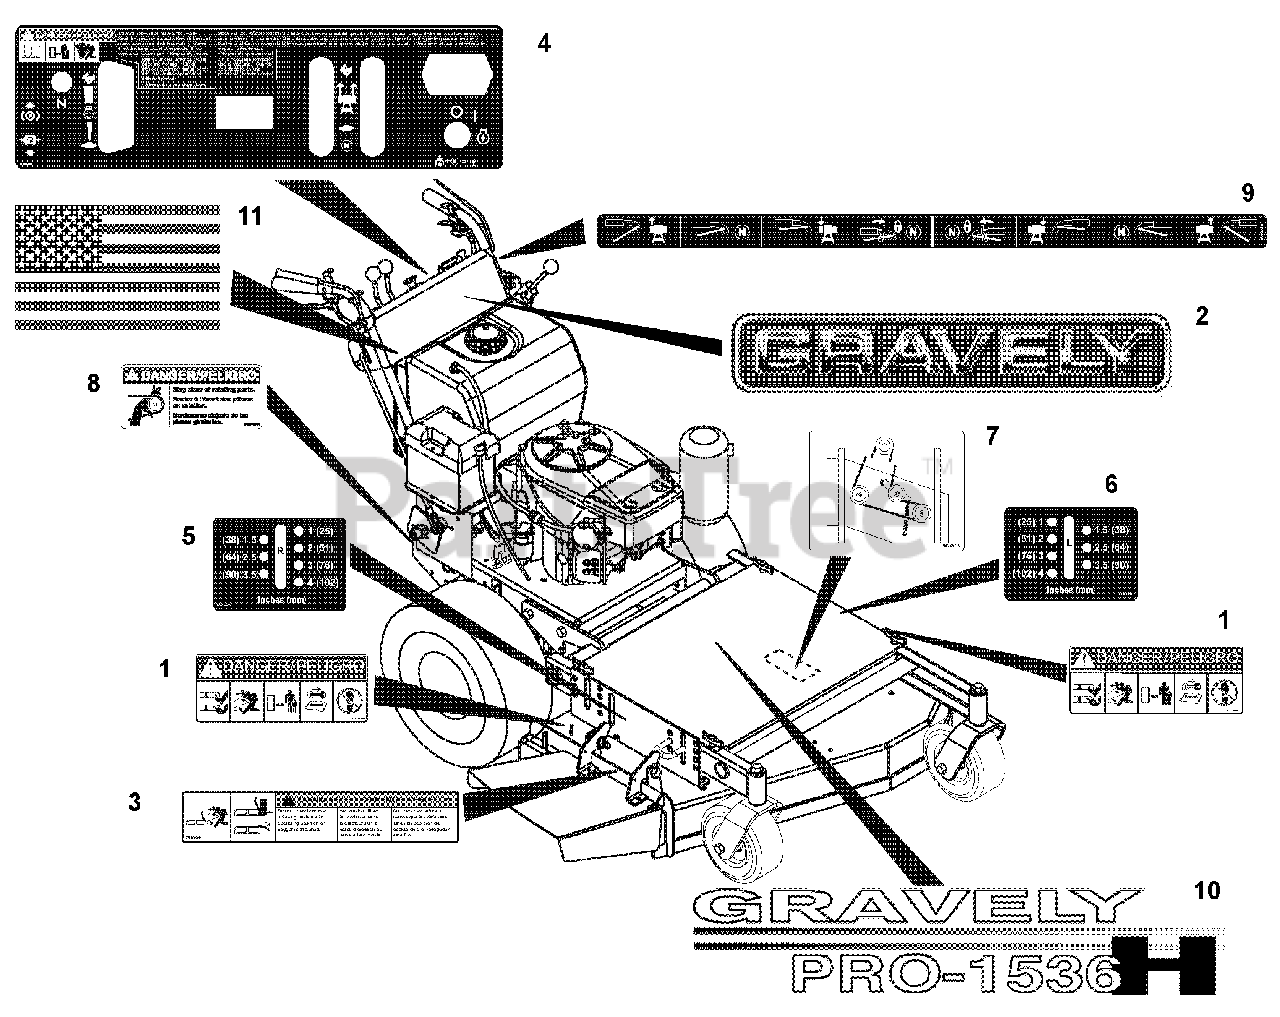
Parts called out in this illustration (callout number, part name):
1	Decal, Mower Pan Head Danger
2	Decal- 15" Gravely Logo
3	Decal, Warning (105, 120, 123)
4	Decal, Control HR15 (105)
5	Decal, Height of Cut-Fixed- Right Hand (105, 120, 123, 124)
6	Decal, Height of Cut-Fixed- Left Hand (105, 120, 123, 124)
7	Decal, Belt Diagram-2 Spindle (105, 120)
8	Decal, Danger-Belt Rotating
9	Decal, Steer Levers (Hydro) (105, 123)
10	Decal, Pro 1536H (105, 120)
11	Decal, American Flag
